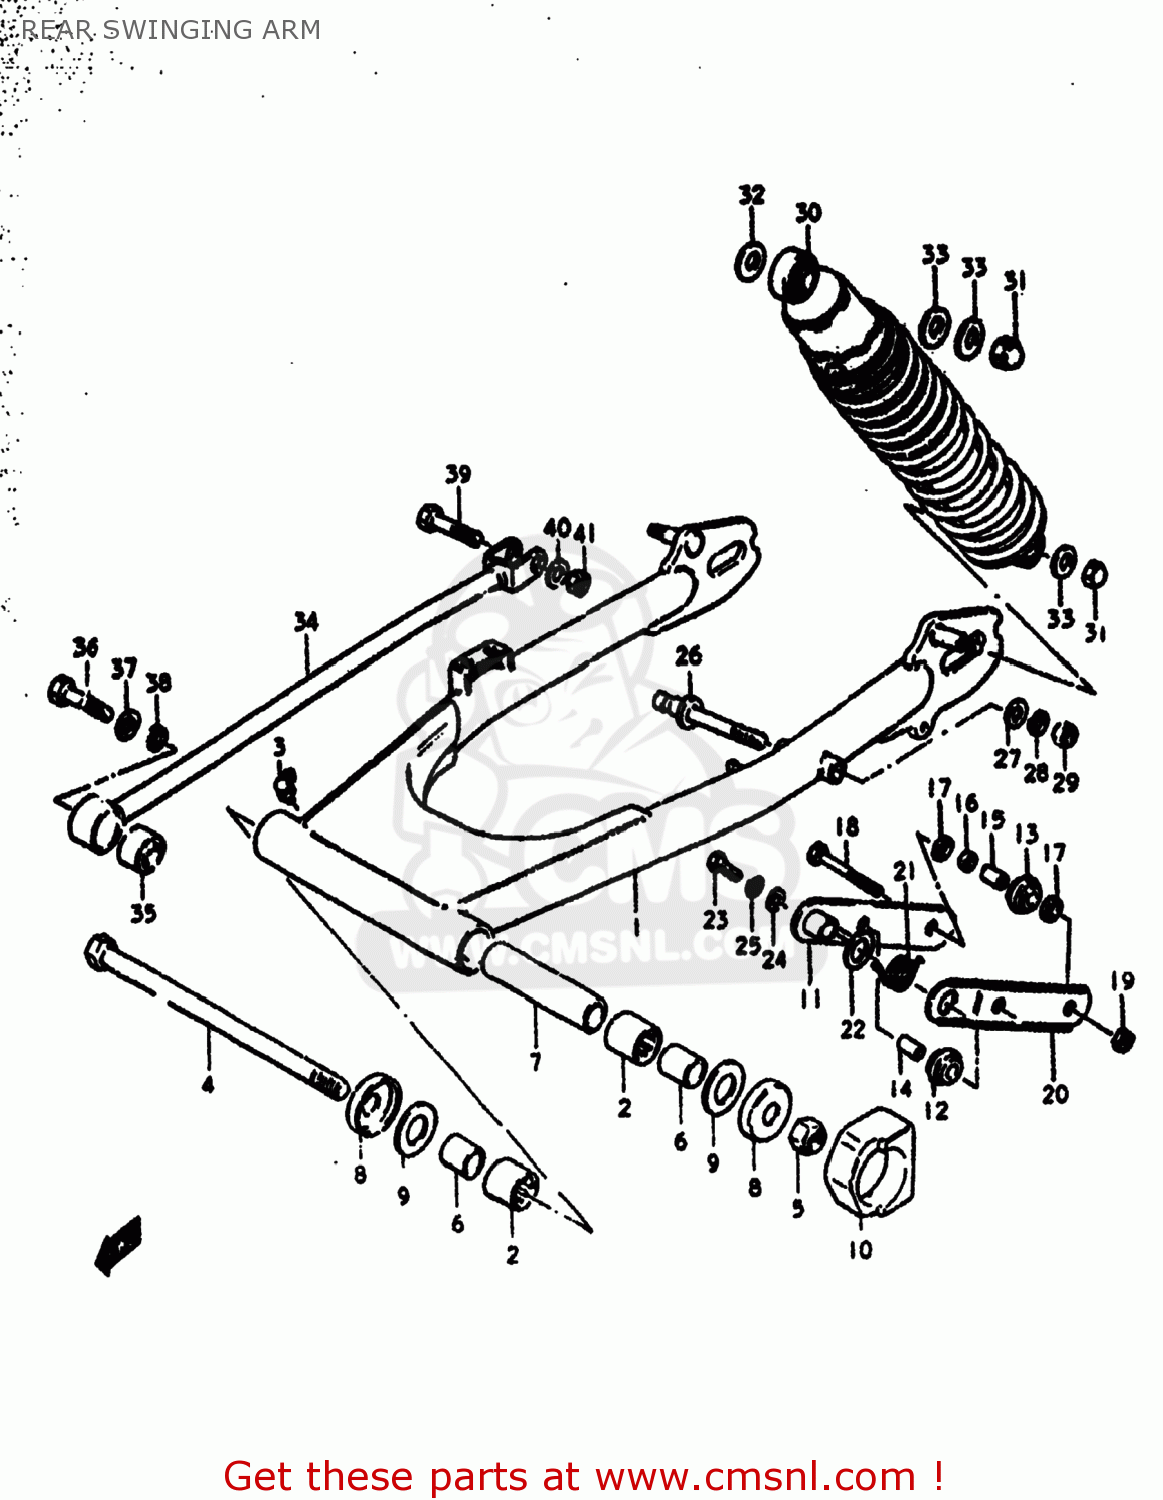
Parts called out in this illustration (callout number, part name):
1	SWING ARM ASSEMBLY,REAR
2	BEARING(22X29X20)
3	NIPPLE,GREASE
4	SHAFT,REAR SWING ARM
5	NUT 14MM
6	SPACER,RR SWGARM PIVOT
7	SPACER
8	COVER,RR SWGARM DUST SEAL
9	WASHER
10	BUFFER,CHAIN TOUCH DEFENSE
11	TENSIONER,CHAIN
12	RUBBER,CHAIN GUARD
13	ROLLER,CHAIN TENSIONER LWR
14	SPACER(6.5X10.5X22.5)
15	SPACER(6.2X10X22.5)
16	BEARING(10X14X15)
17	SEAL,OIL(10X14.4X3.5)
18	BOLT
19	NUT 6MM
20	PLATE,CHAIN TENSIONER
21	SPRING
22	WASHER
23	BOLT
24	WASHER
25	LOCK WASHER
26	HOLDER,CABLE TENSIONER
27	WASHER
28	LOCK WASHER
29	NUT
30	ABSORBER ASSEMBLY,REAR SHOCK
31	NUT, LOWER LH
32	WASHER
33	WASHER
34	TORQUE LINK,REAR
35	BUSH
36	BOLT 10X40
37	WASHER
38	LOCK WASHER
39	BOLT 10X40
40	WASHER
41	NUT
